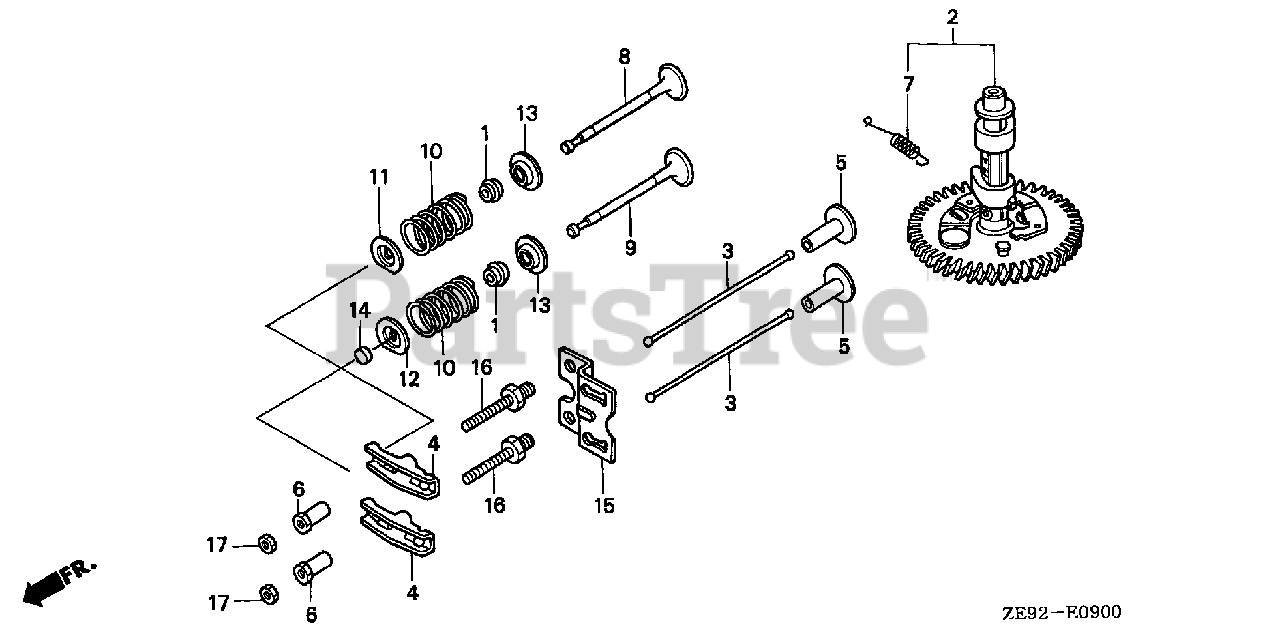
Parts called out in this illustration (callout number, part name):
1	SEAL, VALVE STEM
2	CAMSHAFT ASSY.
3	ROD, PUSH
4	ARM, VALVE ROCKER
5	LIFTER, VALVE
6	PIVOT, ROCKER ARM
7	SPRING, WEIGHT RETURN
8	VALVE, IN. (STELLITE)
9	VALVE, EX. (STELLITE)
10	SPRING, VALVE
11	RETAINER, IN. VALVE SPRING
12	RETAINER, IN. VALVE SPRING
13	SEAT, VALVE SPRING
15	GUIDE, PUSH ROD
16	BOLT, PIVOT (8MM)
17	NUT, PIVOT ADJUSTING
